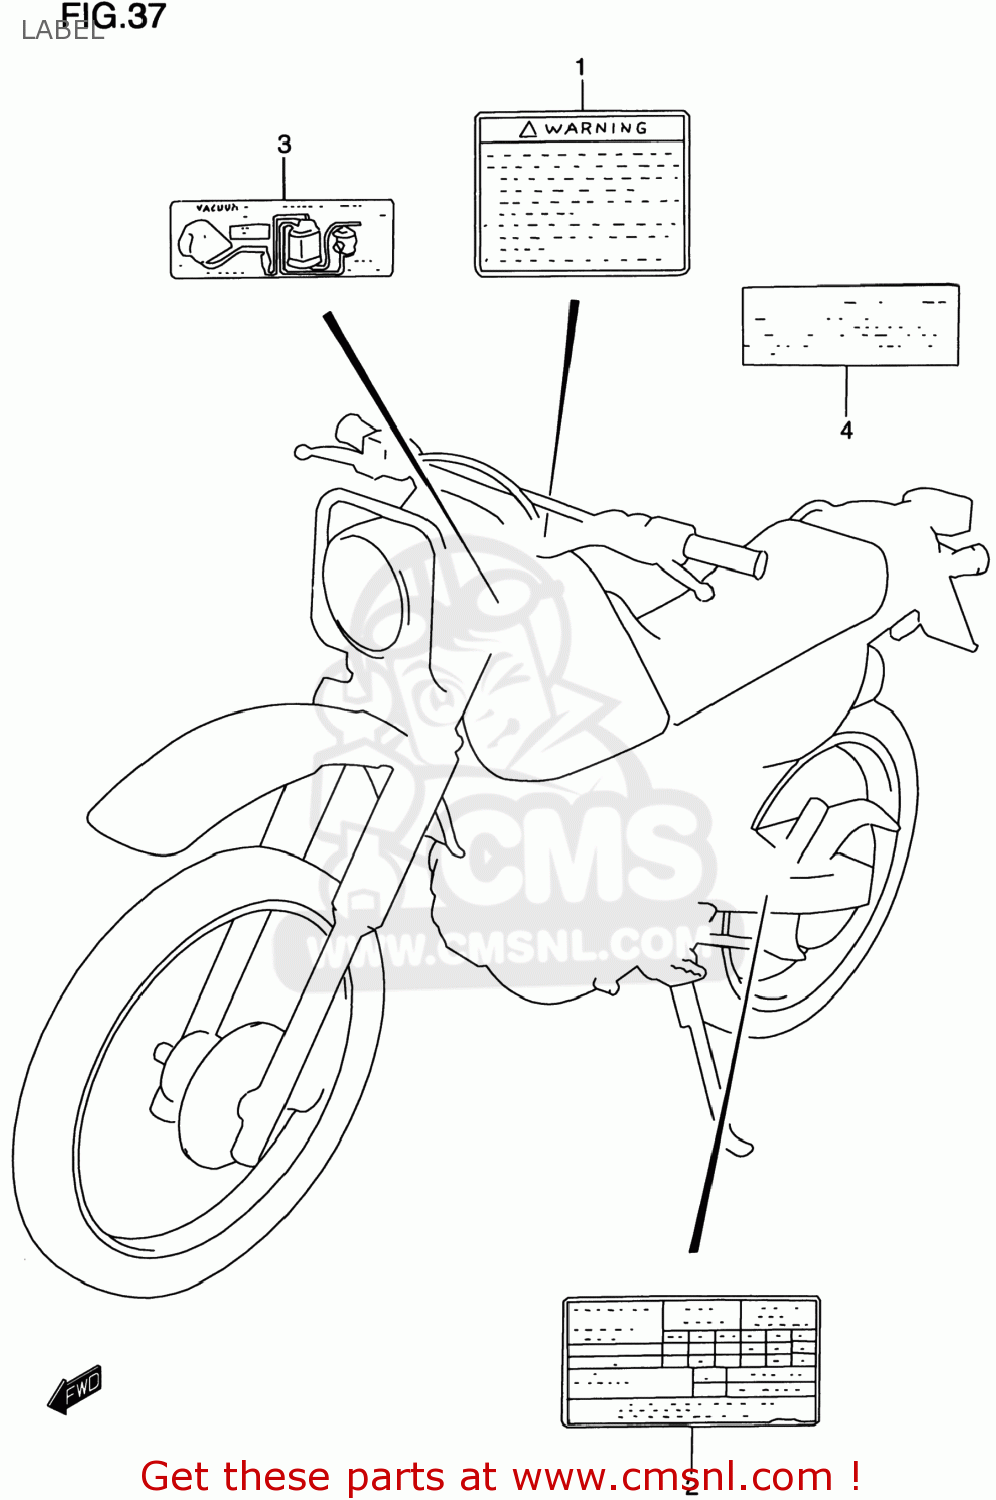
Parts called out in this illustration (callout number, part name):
1	LABEL,GENERAL WARNING
2	LABEL,TIRE INFORMATION
3	LABEL,PIPING DIAG
4	LABEL (MANUAL NOTICE)
5	MANUAL, OWNER'S
